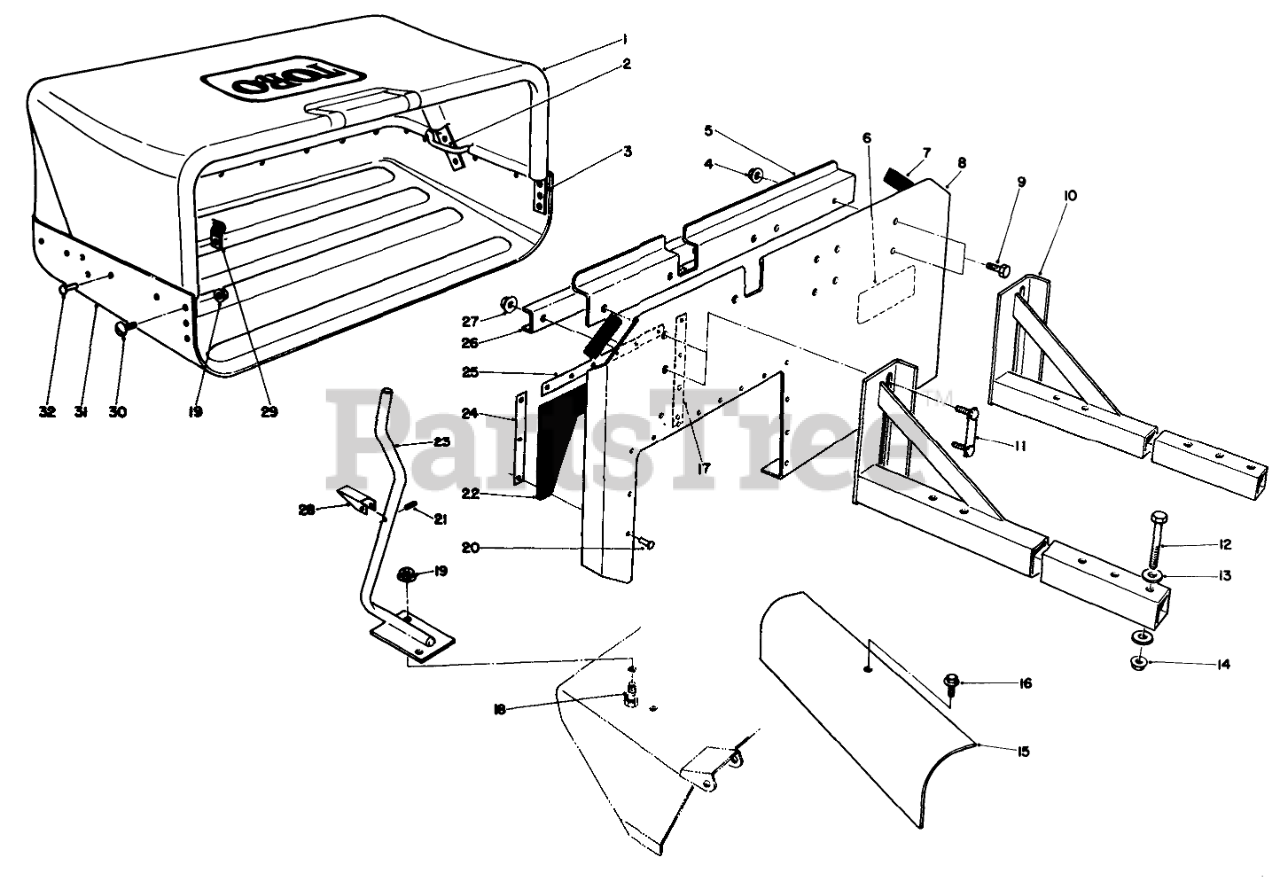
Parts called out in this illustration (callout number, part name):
1	Bag-Cloth
2	Rod-Cloth
3	Tube-Bag Support
4	NUT-HHF, WHIZ
5	Support-Bag
6	DECAL-DANGER
7	PAD-RUBBER
8	Panel-Back
9	SCREW-HH
10	Beam-Mounting
11	Retainer-Bolt
12	SCREW-HH
13	WASHER-FLAT
14	NUT-LOCK, NI
15	Baffle-44in
16	Screw-HH
17	STRIP-Seal, 10in
18	SCREW-HH
19	NUT-HF
20	RIVET-POP
21	PIN-SPRING
22	Seal-Panel Model 30126
23	Rod-Lockup
24	STRIP
25	STRIP-SEAL, 16in
26	Support-Channel
27	NUT-LOCK, FLANGE
28	LATCH-LOCKUP
29	CLIP-HALF
30	SCREW-PPH
31	TRAY-BAG, GRASS
32	RIVET-BLIND
